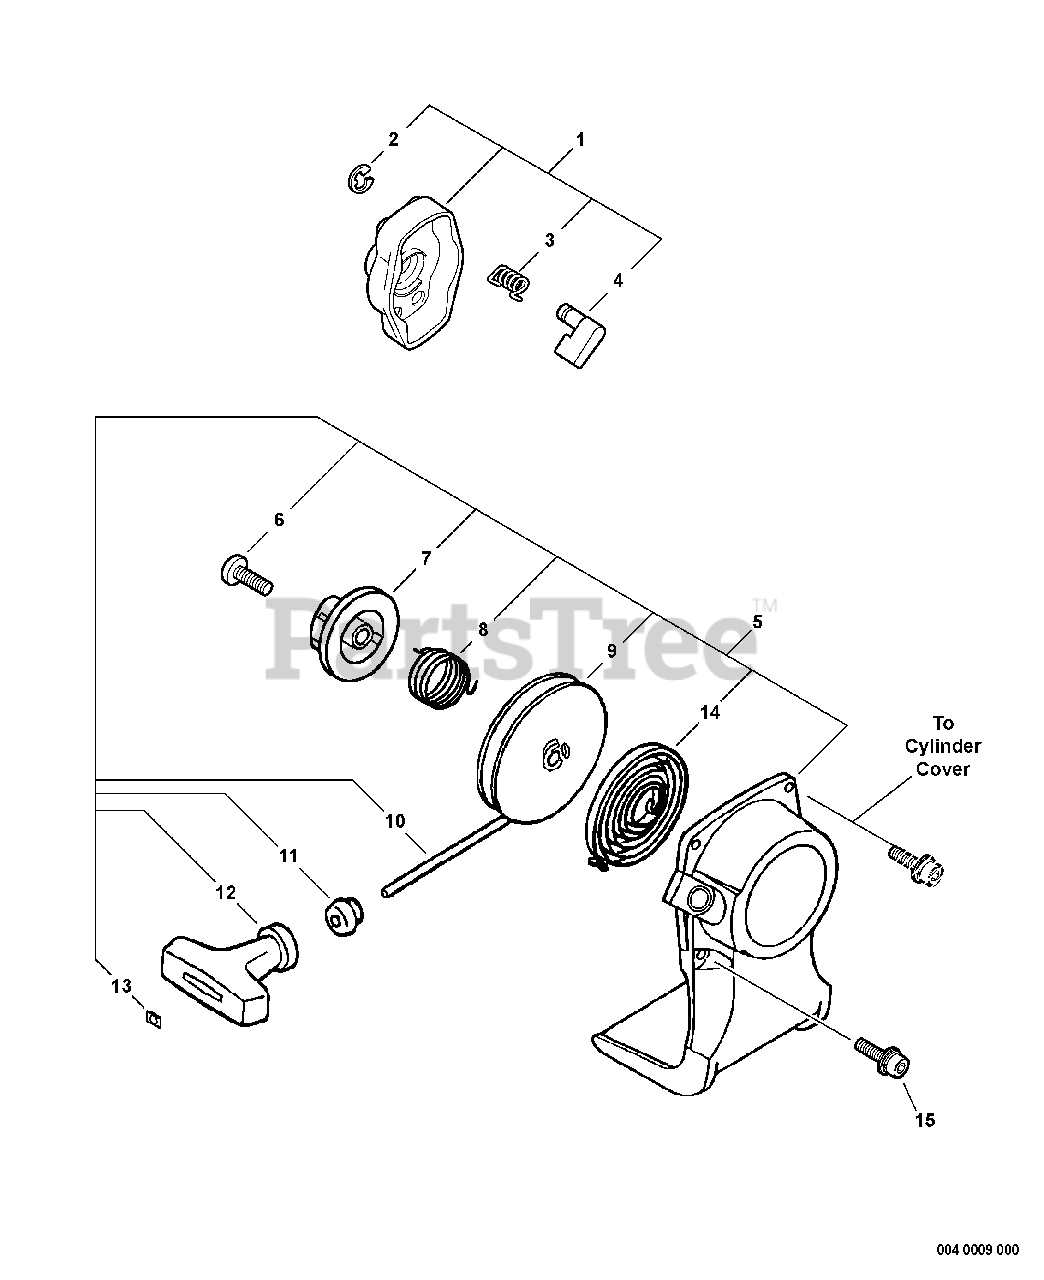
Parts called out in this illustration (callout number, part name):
1	STARTER PAWL ASSY
2	RING, RETAINING - 4
3	SPRING, RETURN
4	PAWL, STARTER
5	STARTER ASSY
6	SCREW
7	PLATE, CAM
8	SPRING, DAMPER
9	REEL, ROPE
10	ROPE, STARTER - 3X700
11	GUIDE, ROPE
12	GRIP, STARTER
13	RETAINER, ROPE
14	SPRING, REWIND
15	SCREW - 4X16
